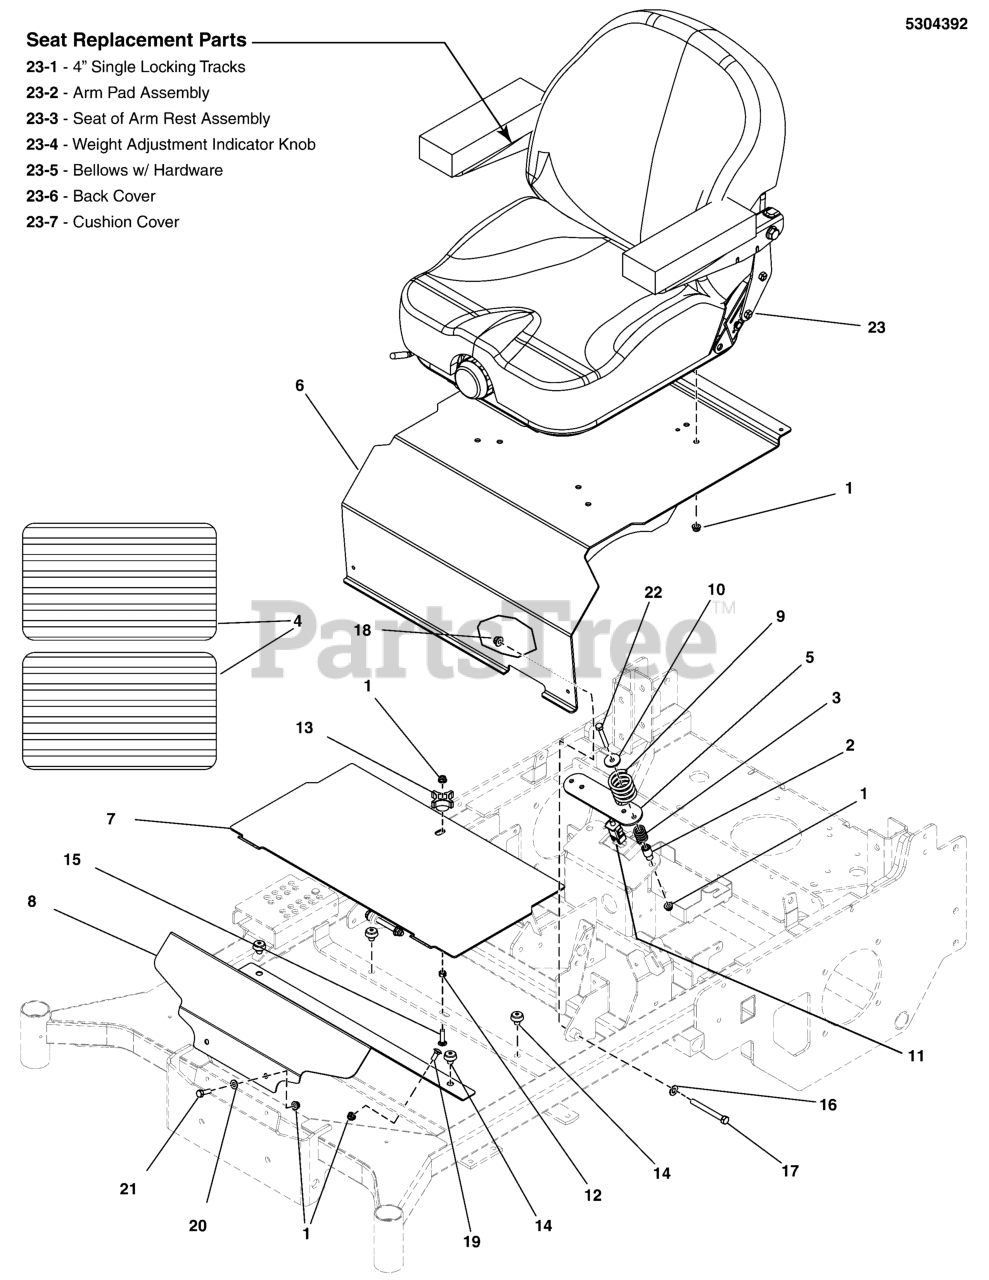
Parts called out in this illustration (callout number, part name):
1	NUT, 5/16-18 HEX NYLOCK FLANGE
2	SPACER, .33 X .66 X 1.31 SHLDR, CZ
3	SPRING, COMP 720ID X 1.310LG X .118WIRE
4	SAFETY WALK, 10.00 X 19.00
5	PLATE, SEAT SWITCH - RED
6	ASSM, SEAT PLATE W/DECALS,200XT-FRS (5413370B)
7	PLATE, REMOVABLE FLOOR, 200XT - RED
8	PLATE, RIGID FLOOR, 200XT - RED
9	SPRING, SEAT SUPPORT
10	WASHER, .34 X 1.25 X 10 GA
11	SWITCH, PLUNGER, NO, SINGLE POLE SNAP-IN
12	NUT, 5/16-18, HEX, CNTR LK,ZINC PHOS/OIL
13	KNOB-INT THR .312-18 4-ARM 2.12WD 1.06LG
14	MNT, VBRTN, RBBR
15	BOLT, 5/16-18 X 1-1/4, CARRIAGE CZ
16	WASHER, 3/8 SAE
17	BOLT, 3/8-16 X 3-1/2" GD5 CZ
18	NUT, 3/8-16 HEX NYLOCK FLANGE
19	BOLT, 5/16-18 X 3/4, CARRIAGE
20	WASHER, 5/16" SAE
21	BOLT, 5/16-18 X 1 GD5 CZ
22	BOLT, 5/16-18 X 2-1/4 GD5 YZ
23	SEAT, MID BACK, W/SUSPENSION, SEATS INC
23-1	4" SINGLE LOCKING TRACKS BASE
23-2	ARM PAD ASSEMBLY BLK/CHAR CAR FIB/HARBR GRY RED WELT
23-3	SET OF ARMREST ASSEMBLY BLK/CHAR CAR FIB/HARBR GRY RED WELT
23-4	WEIGHT ADJUST INDICATOR KNOB ASSY BASE
23-5	BELLOWS W/ HARDWARE BASE
23-6	BACK COVER FOR FIXED BACK I3M BLK/CHAR CAR FIB/HARBR GRY RED WELT
23-7	CUSHION COVER FOR I3M BLK/CHAR CAR FIB/HARBR GRY RED WELT
